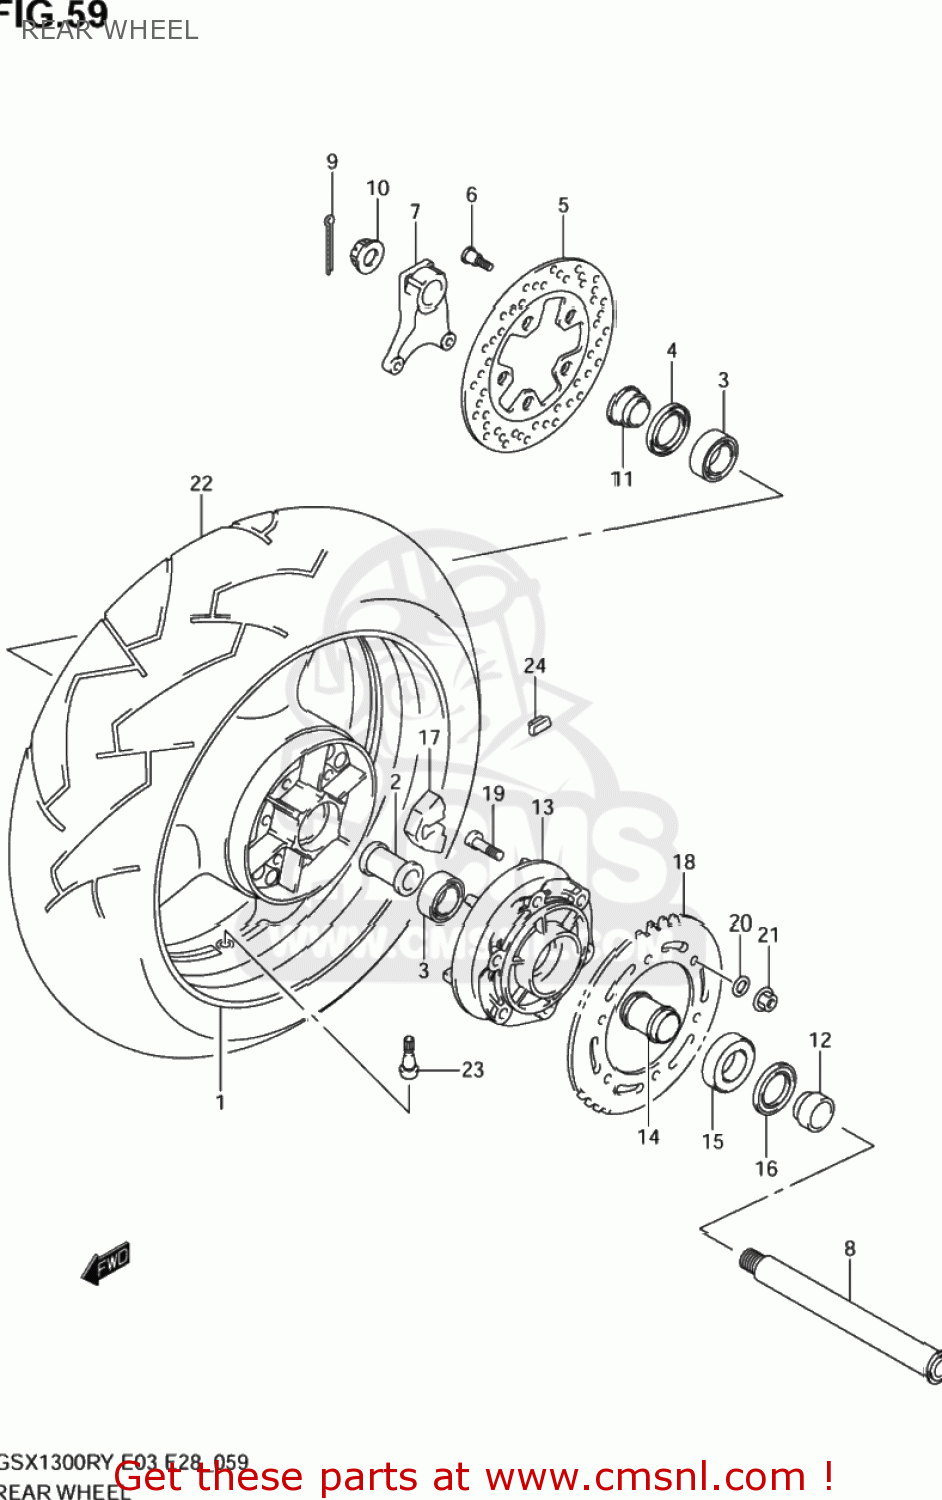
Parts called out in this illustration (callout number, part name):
1	WHEEL,REAR,17X
2	SPACER,RR HUB BEARING
3	BEARING(32X58X13)
4	SEAL,OIL(38X58X7)
5	DISC,RR BRAKE
6	BOLT 8X33
7	BRACKET,RR CALIPER
8	AXLE,RR
9	PIN, COTTER
10	NUT
11	SPACER,RR AXLE,R
12	SPACER,RR AXLE,L
13	DRUM,RR SPROCKET
14	RETAINER,RR SPROCKET DRUM
15	BEARING
16	SEAL,OIL(39X65X7)
17	ABSORBER,RR HUB SHOCK
18	SPROCKET,RR(NT:40-530)
19	BOLT
20	WASHER
21	NUT
22	TIRE,REAR 190/50 ZR17
23	VALVE ASSY,WHEEL RIM(TR412)
24	BALANCER,WHEEL (10G)
